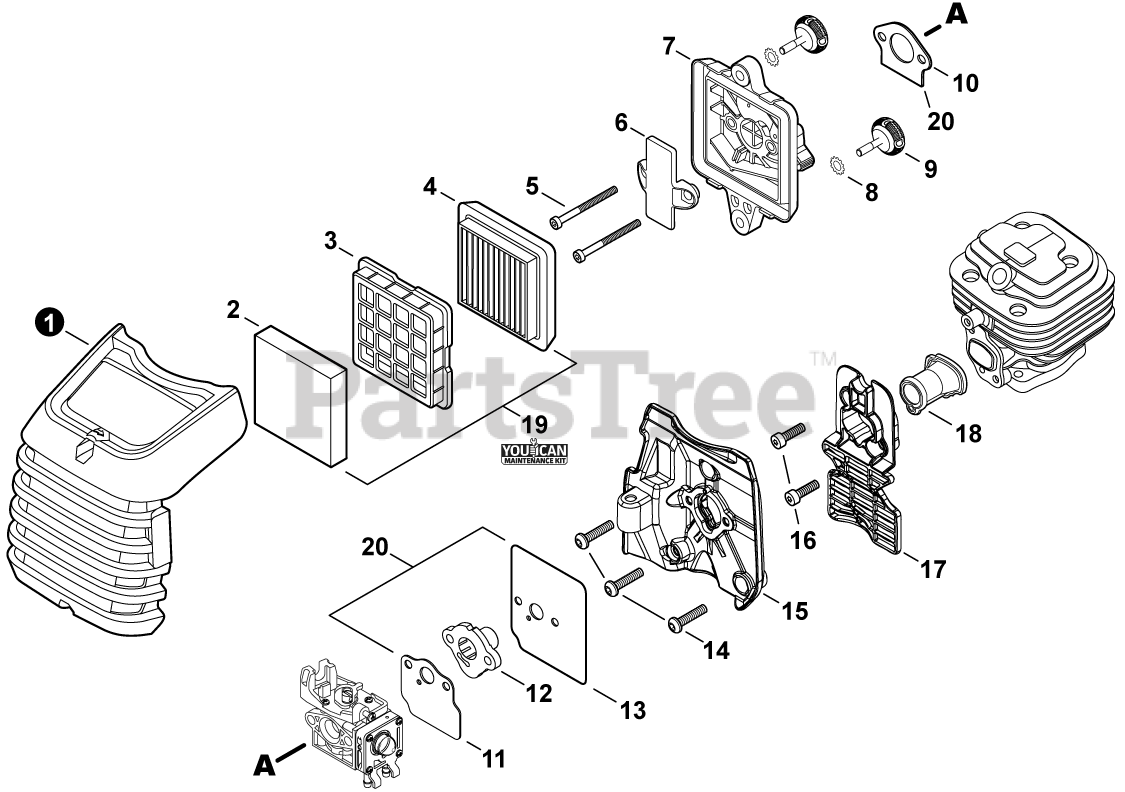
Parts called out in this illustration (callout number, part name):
1	COVER, AIR FILTER
2	PRE-FILTER, FOAM
3	RETAINER, PRE-FILTER
4	FILTER, AIR
5	BOLT, TORX 5x60
6	PLATE, PREVENT
7	CASE, AIR FILTER
8	WASHER, LOCK
9	THUMBSCREW
10	GASKET, INTAKE
11	GASKET, BOOT
12	BOOT, INTAKE
13	GASKET, INSULATOR PLATE
14	BOLT, TORX 5x16
15	PLATE, INSULATOR
16	BOLT, TORX 5x16
17	HOLDER, BELLOWS
18	BELLOWS, INTAKE
19	TUNE-UP KIT - YOUCAN™
20	GASKET KIT: ENGINE, INTAKE, EXHAUST
